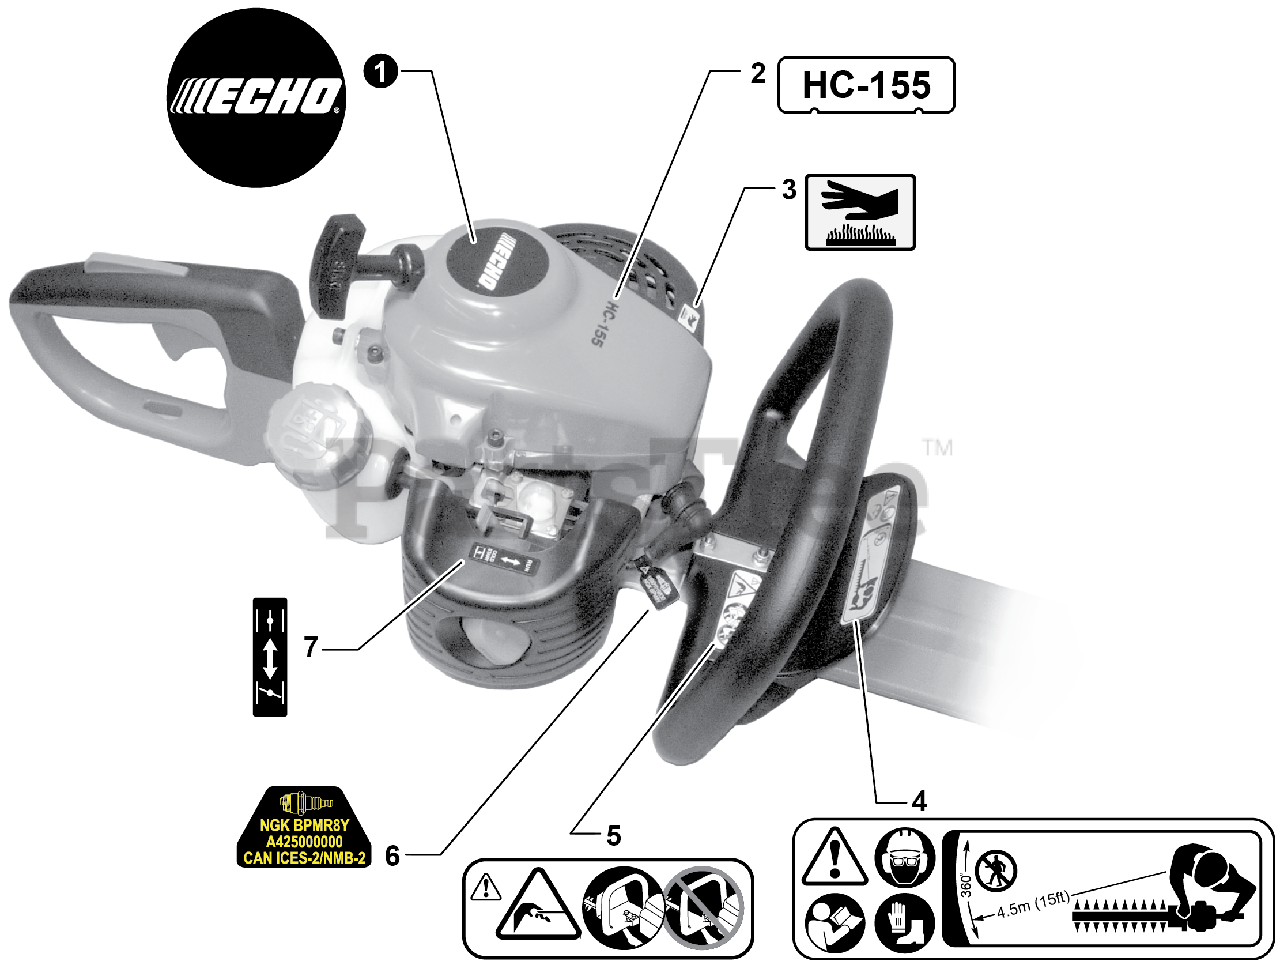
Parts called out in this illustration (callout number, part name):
1	LABEL - STARTER - ECHO
2	LABEL - MODEL - HC-155
3	LABEL - CAUTION - HOT
4	LABEL - CAUTION - ISO
5	LABEL - CAUTION
6	LABEL - SPARK PLUG - BPMR8Y
7	LABEL - CHOKE
